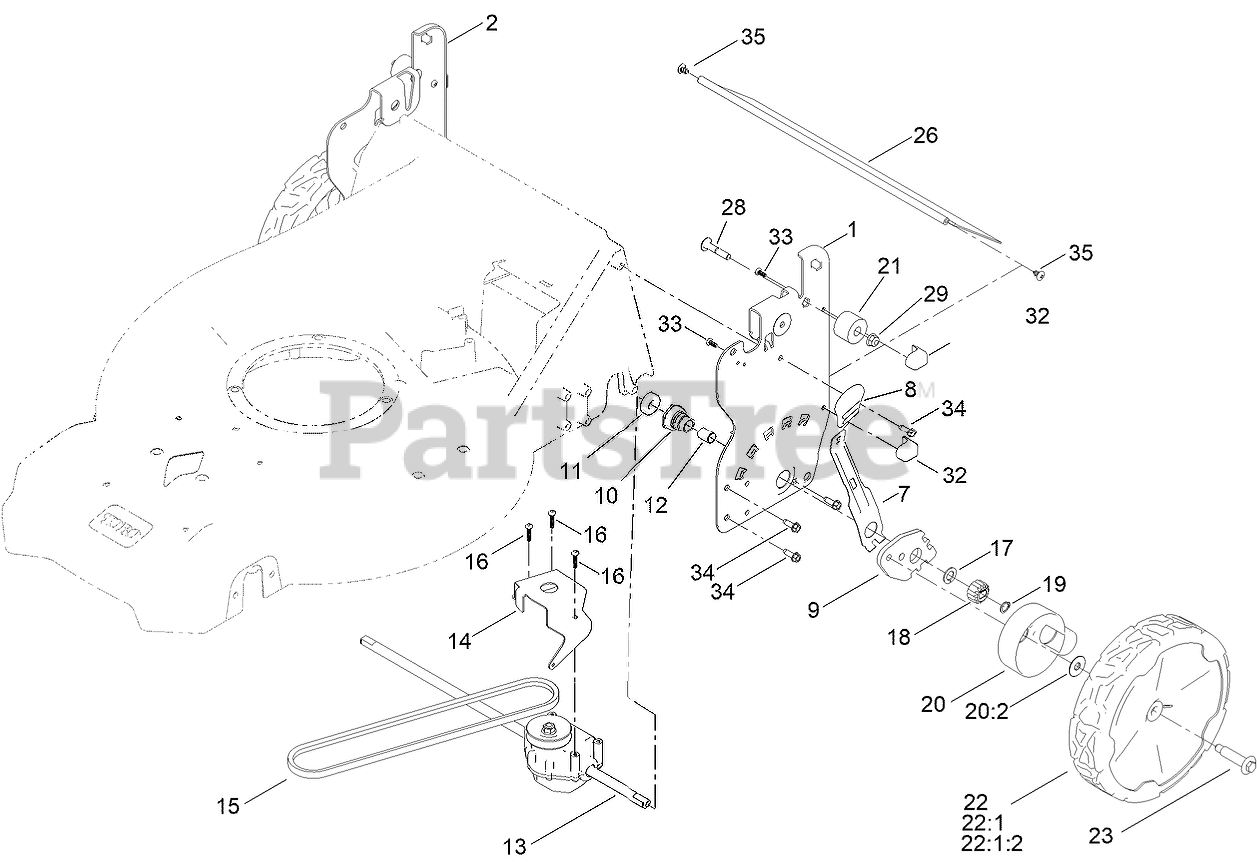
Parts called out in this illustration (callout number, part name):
1	PLATE-HOC, LH
2	PLATE-HOC, RH (ISO)
7	ARM-SPRING
8	KNOB-HOC
9	ARM-PIVOT, REAR
10	RETAINER-BUSHING, HOC
11	BEARING-WHEEL
12	BUSHING-SLEEVE
13	TRANSMISSION-RWD, 5.25:1
14	BRACKET-TRANS, RWD HI
15	BELT-V
16	SCREW-PLASTITE
17	WASHER-THRUST
18	GEAR-PINION, 15T
19	RING-RETAINING
20	ASM-COVER, GEAR
20:2	WASHER-STEPPED
21	BUMPER-ISOLATOR
22	ASM-9.65" WHEEL, GEARED
22:1	ASM-WHEEL, 9.65" (BEARINGS)
22:1:2	BEARING-WHEEL
23	WHEEL BOLT
26	SHIELD-TRAILING
28	SCREW-HH
29	NUT-HF
32	PAD-SMART STOW
33	SCREW-PLASTITE
34	SCREW-HWHTF
35	SCREW-PTH
